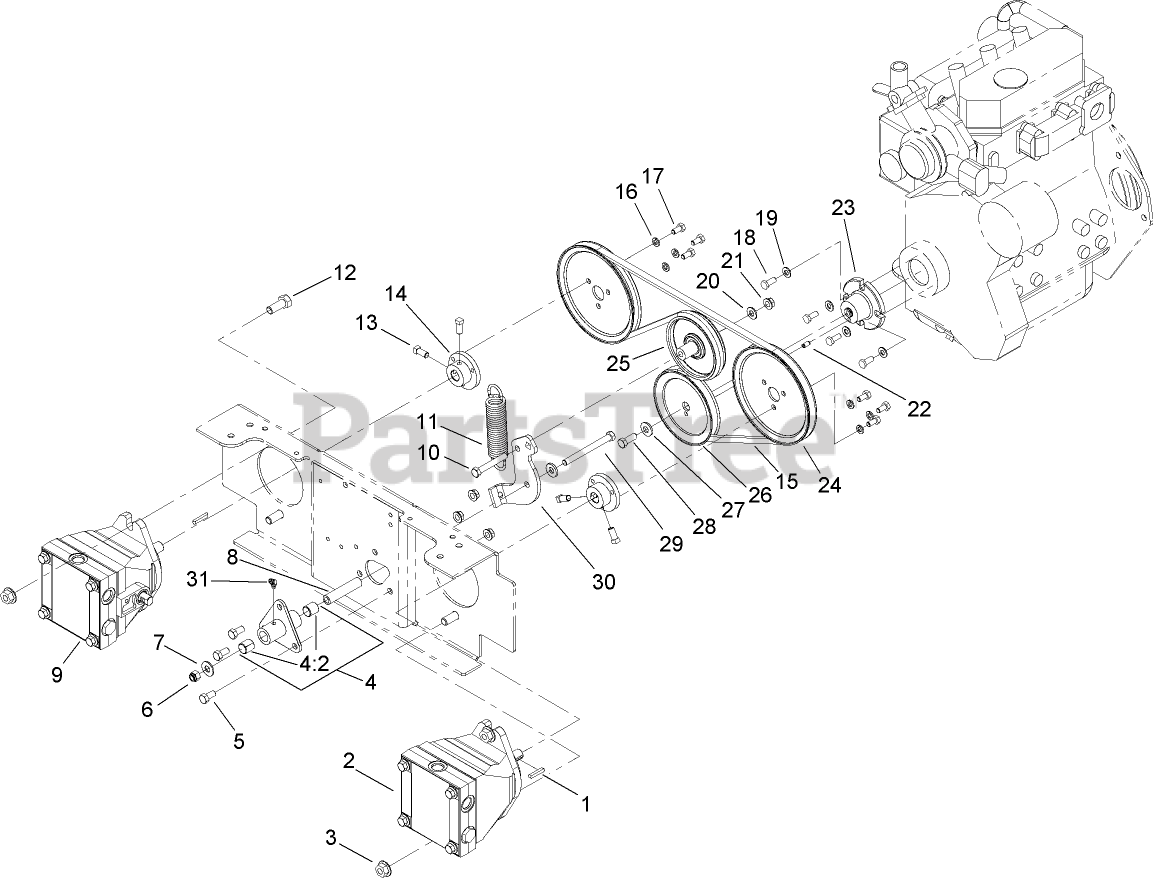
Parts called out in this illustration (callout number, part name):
2	PUMP-HYDRO, LH
3	NUT-HHF
4	PUMP IDLER ASM
4:2	SLEEVE-BEARING
5	SCREW-HH
6	NUT-LOCK, NI
7	WASHER-FLAT
8	BUSHING-TIGHTENER, PIVOT
9	PUMP-HYDRO, RH
10	SCREW-HH
11	Spring-Extension
12	SCREW-HH
13	SCREW-SET
14	HUB-PUMP
15	BELT-V
16	WASHER-LOCK
17	SCREW-HH
18	SCREW-HH
19	WASHER-PLAIN
20	WASHER-FLAT
21	NUT-HHF, WHIZ
22	PIN-ROLL
23	HUB-DRIVE, PUMP
24	SHEAVE-PUMP
25	IDLER-PUMP
26	SHEAVE-ENGINE
27	WASHER-BELLEVILLE
28	SCREW-HH
29	SCREW-HH
30	ARM-TIGHTENER, PUMP
31	FITTING-LUBE, 45 DEG
